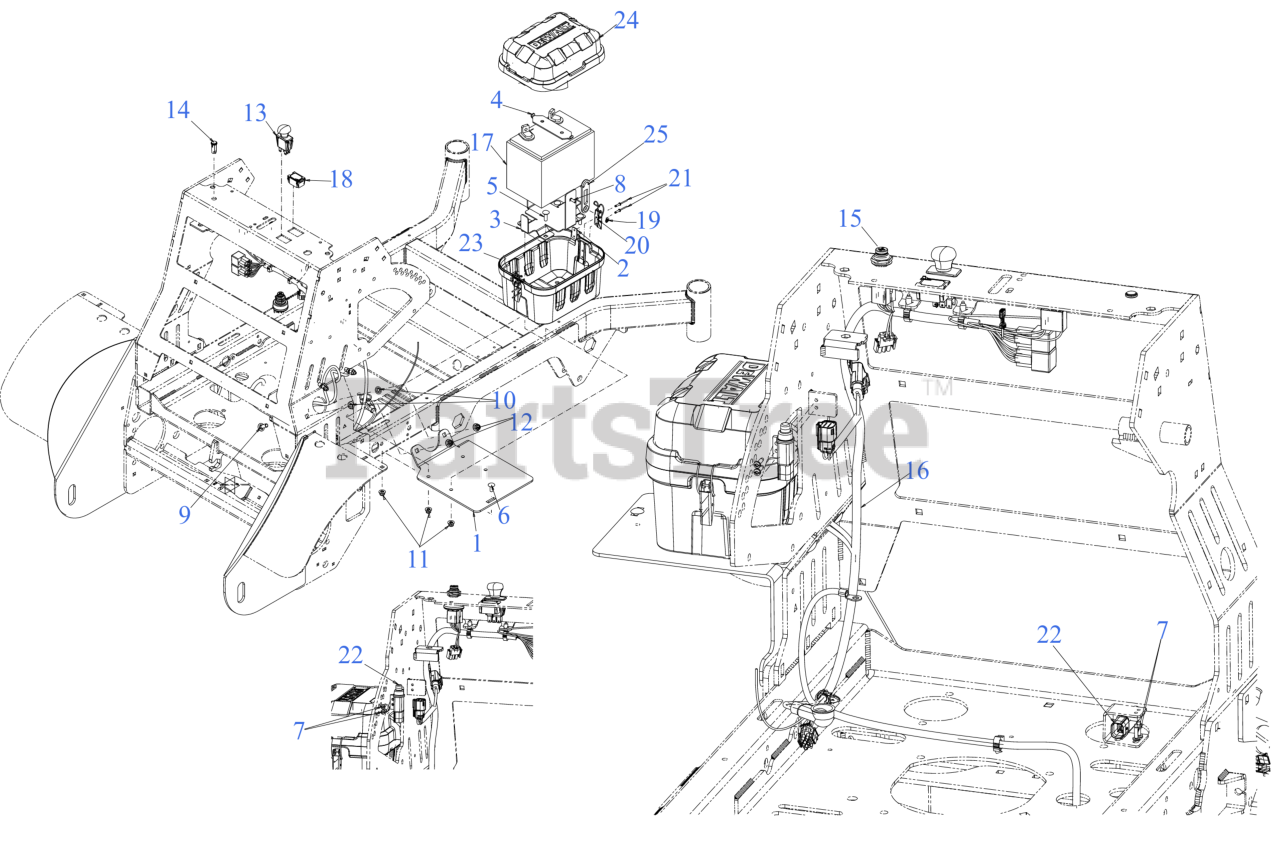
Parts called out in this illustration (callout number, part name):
1	BATTERY MOUNT BRACKET
2	BACK CLIP PLATE
3	BATTERY MOUNT
4	BATTERY STRAP
5	CARRIAGE BOLT 5/16-18 x 1.00
6	CARRIAGE BOLT 5/16-18 x .75
7	SCREW (10-24X.75:PH:TAP:T25:GR5)
8	SCREW 1/4-20 x .75 GR5
9	CARRIAGE BOLT 3/8-16 x 1.00 GR5
10	PUSH NUT
11	FLANGE LOCK NUT 5/16-18
13	PTO SWITCH (BLACK KNOB) TEXT SYM
14	INDICATOR LIGHT-RED
15	KEY SWITCH
16	HARNESS (EFI KAW)
17	BATTERY (230 CCA AGM U1-280)
18	HOUR METER
19	RETAINER-BOLT .25ID x .50OD
21	RIVOT
22	SEALED PLUNGER SWITCH
23	BATTERY BOX (LOWER)
24	BATTERY BOX (UPPER)
25	COVER STRAP 2.50 LONG
